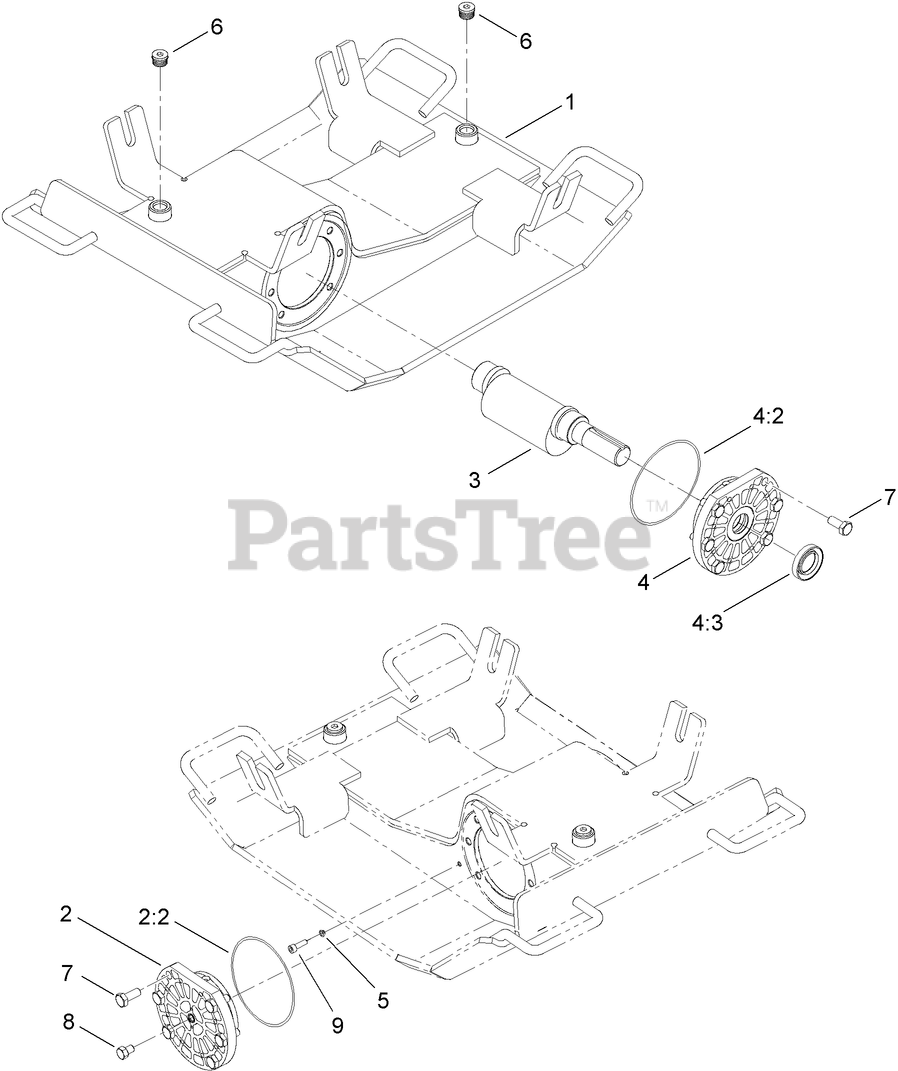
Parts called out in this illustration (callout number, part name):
2	PLATE CAP BEARING ASM (BLIND END)
2:2	O-RING
3	SHAFT-ECCENTRIC
4	PLATE CAP BEARING ASM (SHEAVE END)
4:2	O-RING
4:3	SEAL-SHAFT
5	WASHER-SEALING, NYLTITE
6	FITTING-HYD
7	SCREW-HH
8	SCREW-HH
9	SCREW-HSH
